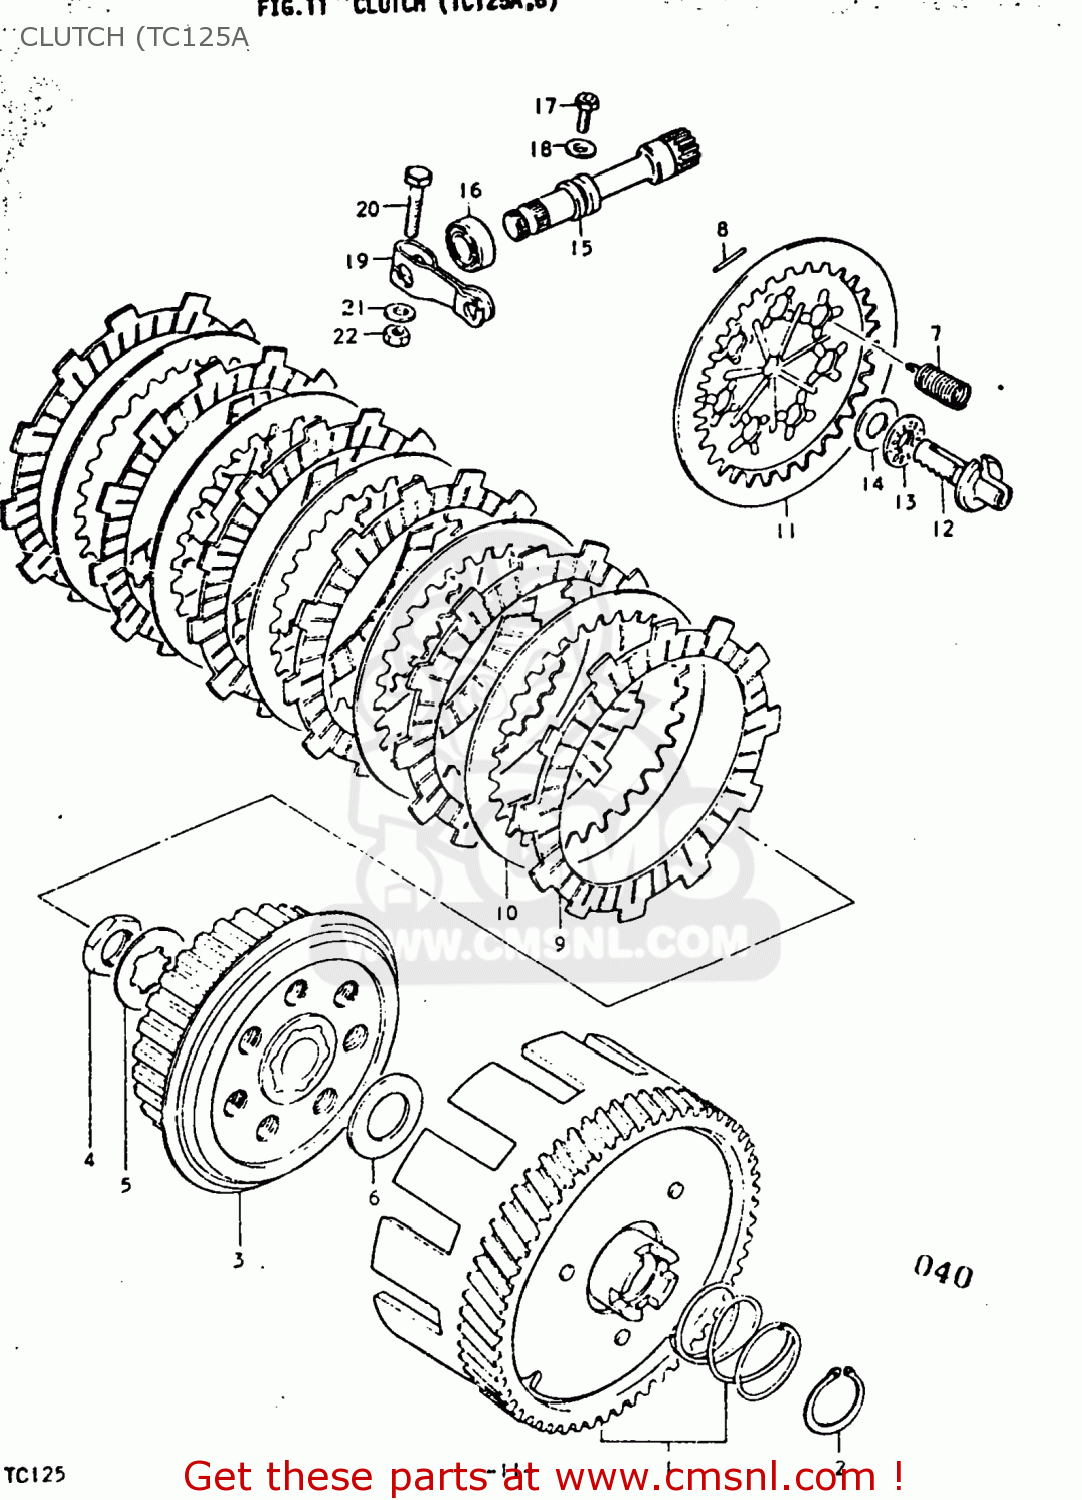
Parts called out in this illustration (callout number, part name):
1	GEAR ASSEMBLY,PRIMARY DRIVE
2	SPRING
3	HUB,CLUTCH SLEEVE
4	NUT
5	WASHER,LOCK
6	WASHER
7	SPRING
8	PIN(2.5X19.8)
9	PLATE,CLUTCH DRIVE
10	PLATE,CLUTCH DRIVEN (NAS)
11	PLATE,CLUTCH PRESSURE
12	RACK,CLUTCH RELEASE
13	BEARING(10X22X2.8)
14	WASHER(10.1X21.4X0.8)
15	PINION,CLUTCH RELEASE
16	OIL SEAL
17	BOLT(6X12)
18	WASHER
19	ARM,CLUTCH RELEASE
20	BOLT
21	WASHER
22	NUT
